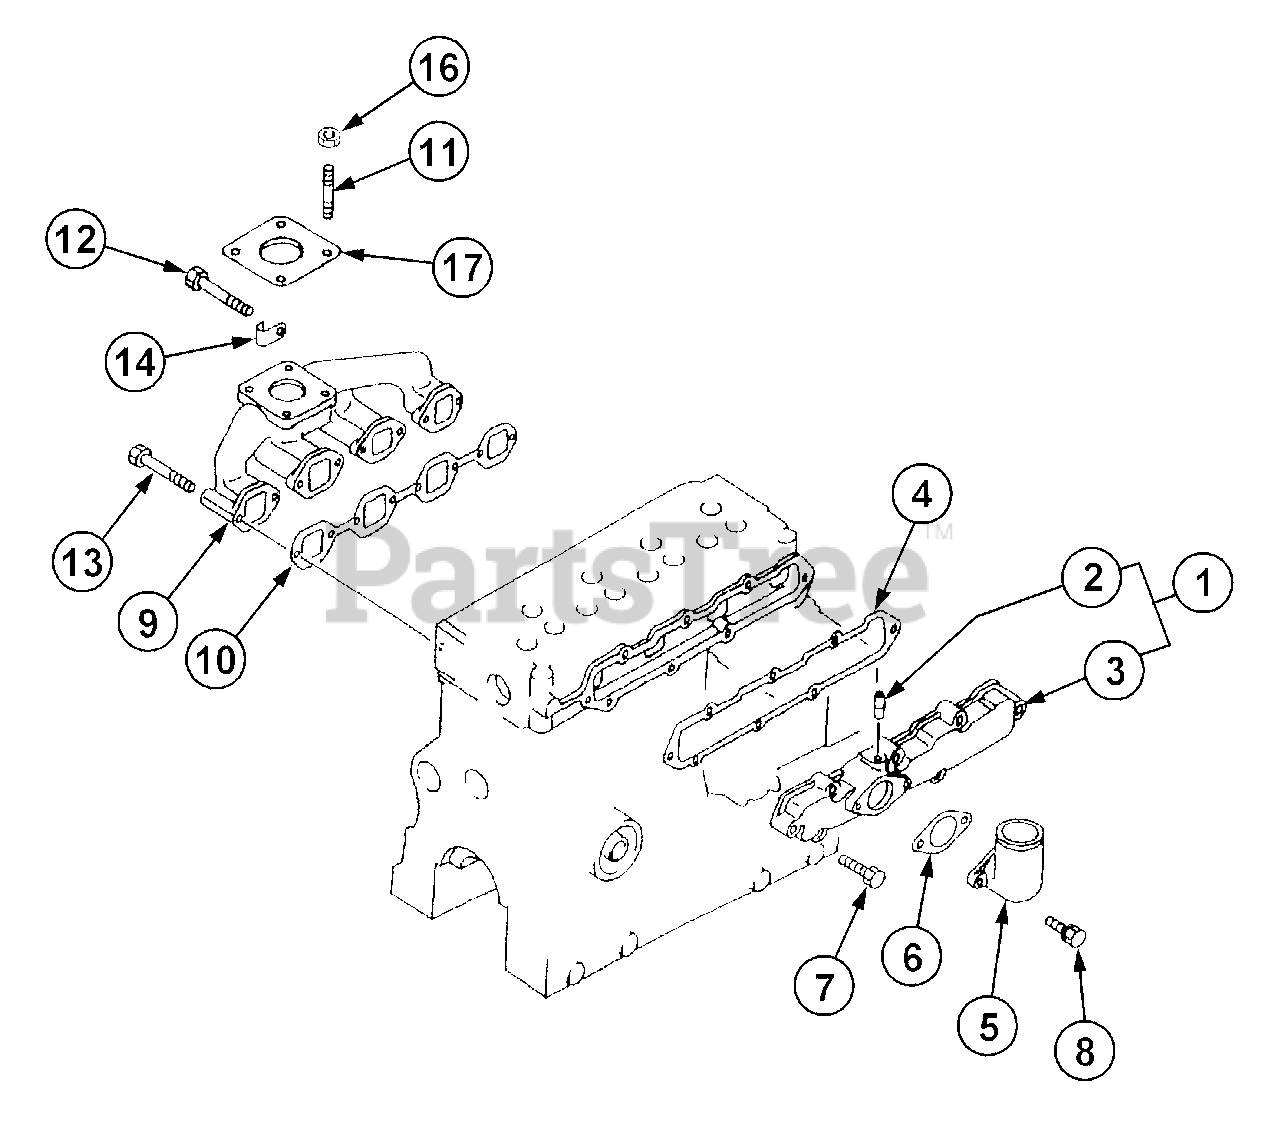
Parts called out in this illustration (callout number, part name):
1	Cover Assy, Inlet
2	Pipe
3	Cover, Inlet
4	Gasket, Cover
7	Bolt, w/Washer
8	Bolt, w/Washer
9	Manifold, Exhaust
10	Gasket, Manifold
11	Stud
17	Gasket, Muffler
